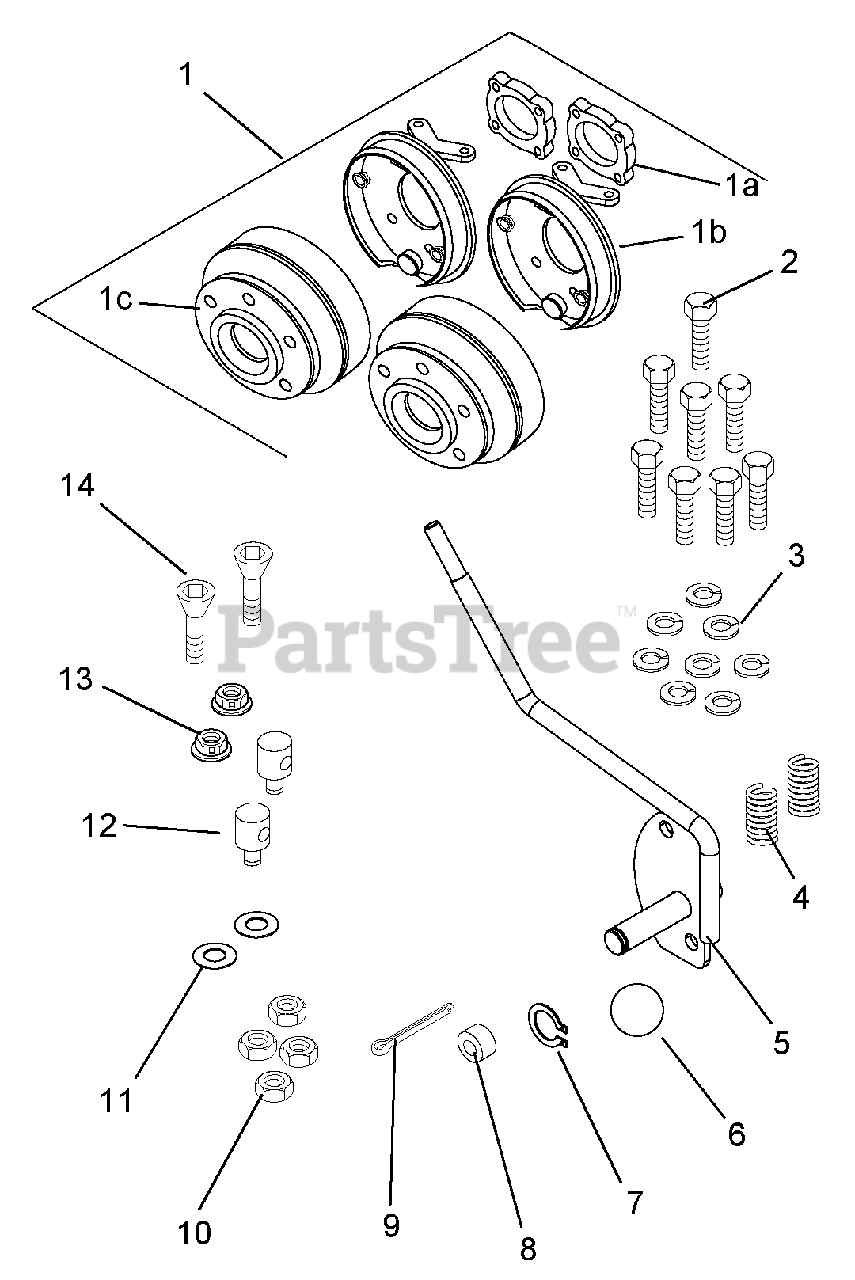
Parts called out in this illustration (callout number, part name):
1	ASSEMBLY, BRAKE
1	KIT, MZ BRAKE (2-SIDE)
2	@BLT-HEX .31-18X1.50 GR5 YWZC
3	@WSHR-LK .31X.078 REG YWZC
4	SG-COMP .142 X .710 X 1.75
5	WMT, BRAKE ACTUATING LEVER
6	KNOB-STEERING LOCK
7	RG-RTNG-EXT .625X.050
8	BSHG-SLV .377X.624X.235
9	@PIN-CTR .09X.75 EXTPRSQCT YWZ
10	@NUT-HEX .38-16 YWZC
11	@WSHR-FL-STL.406X.812X.065 YWZ
12	PIN, PIVOT/TRUNNION
13	@NUT-LK-TOP-FLG .31-18 YWZC
14	SCREW-MACH.31-18X1.5 FLTCNTRSK
